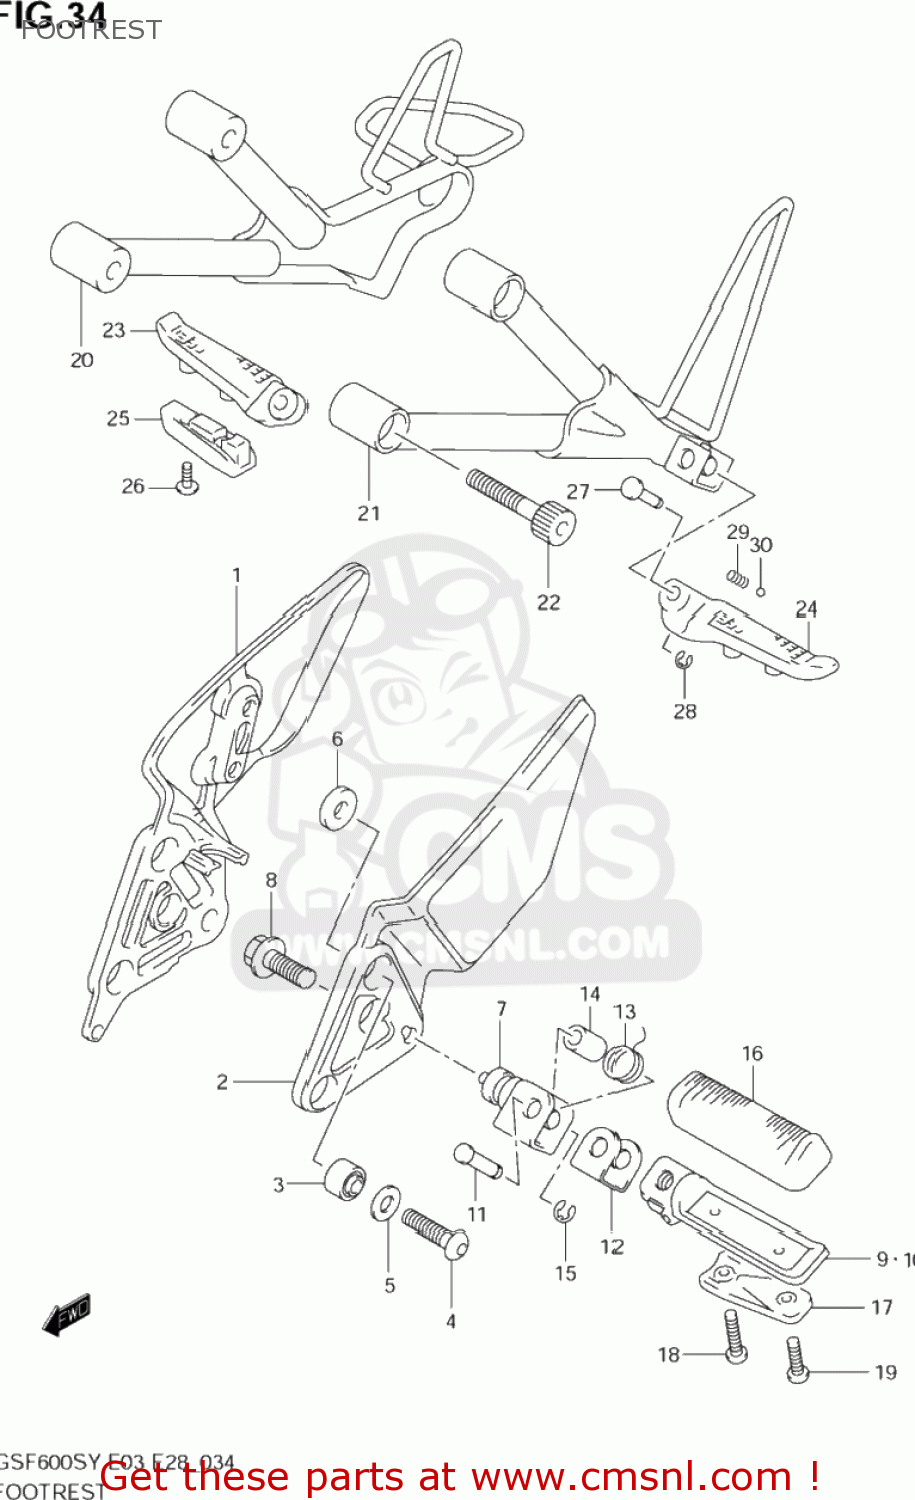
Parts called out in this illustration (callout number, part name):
1	BRACKET,FR FOOTREST,R
2	BRACKET,FR FOOTREST,L
3	BUSH(8.4X20X16)
4	BOLT(8X30)
5	WASHER(13.7X24X2)
6	WASHER(17.2X24X2.2)
7	HOLDER,FOOTREST
8	BOLT(10X28)
9	BAR,FOOTREST,R
10	BAR,FOOTREST,L
11	PIN(8X33.2)
12	CUSHION,FR FOOTREST
13	SPRING
14	SPACER(8.1X12X22)
15	E.RING
16	RUBBER,FOOTREST
17	BALANCER,FR FOOTREST
18	SCREW
19	SCREW
20	BRACKET COMP,PILLION,FOOTREST
21	BRACKET COMP,PILLION,FOOTREST
22	BOLT
23	BAR,PILLION FOOTREST,RIGHT
24	BAR,PILLION FOOTREST,LEFT
25	BALANCER,PILLION FOOTREST
26	SCREW (5X8)
27	PIN
28	E-RING
29	SPRING
30	BALL
